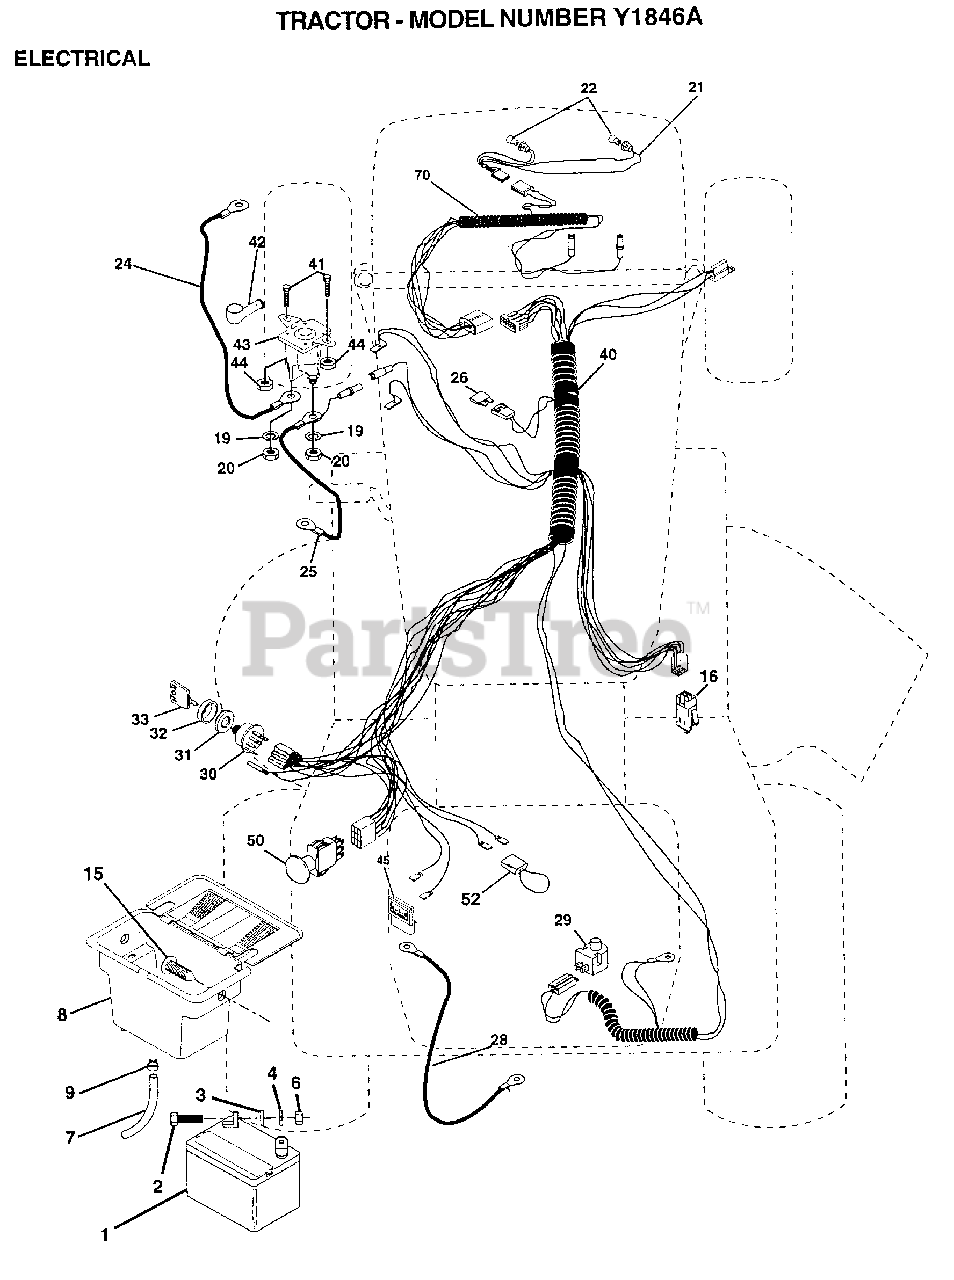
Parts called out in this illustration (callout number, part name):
1	EXT SPRING
2	NUT HXKEP 1/4X20
3	WASHER
5	BOLT.SHLD.5/16-18
6	BRKT HOOD RH
7	BRKT HOOD LH
8	SCREW SLTD HXHD
9	NUT
10	"BRACE,HOOD"
11	HOOD.IMPREG.MS550
13	GRILL (BLACK)
16	NUT
18	WASHER
19	LOCKWASHER GT
